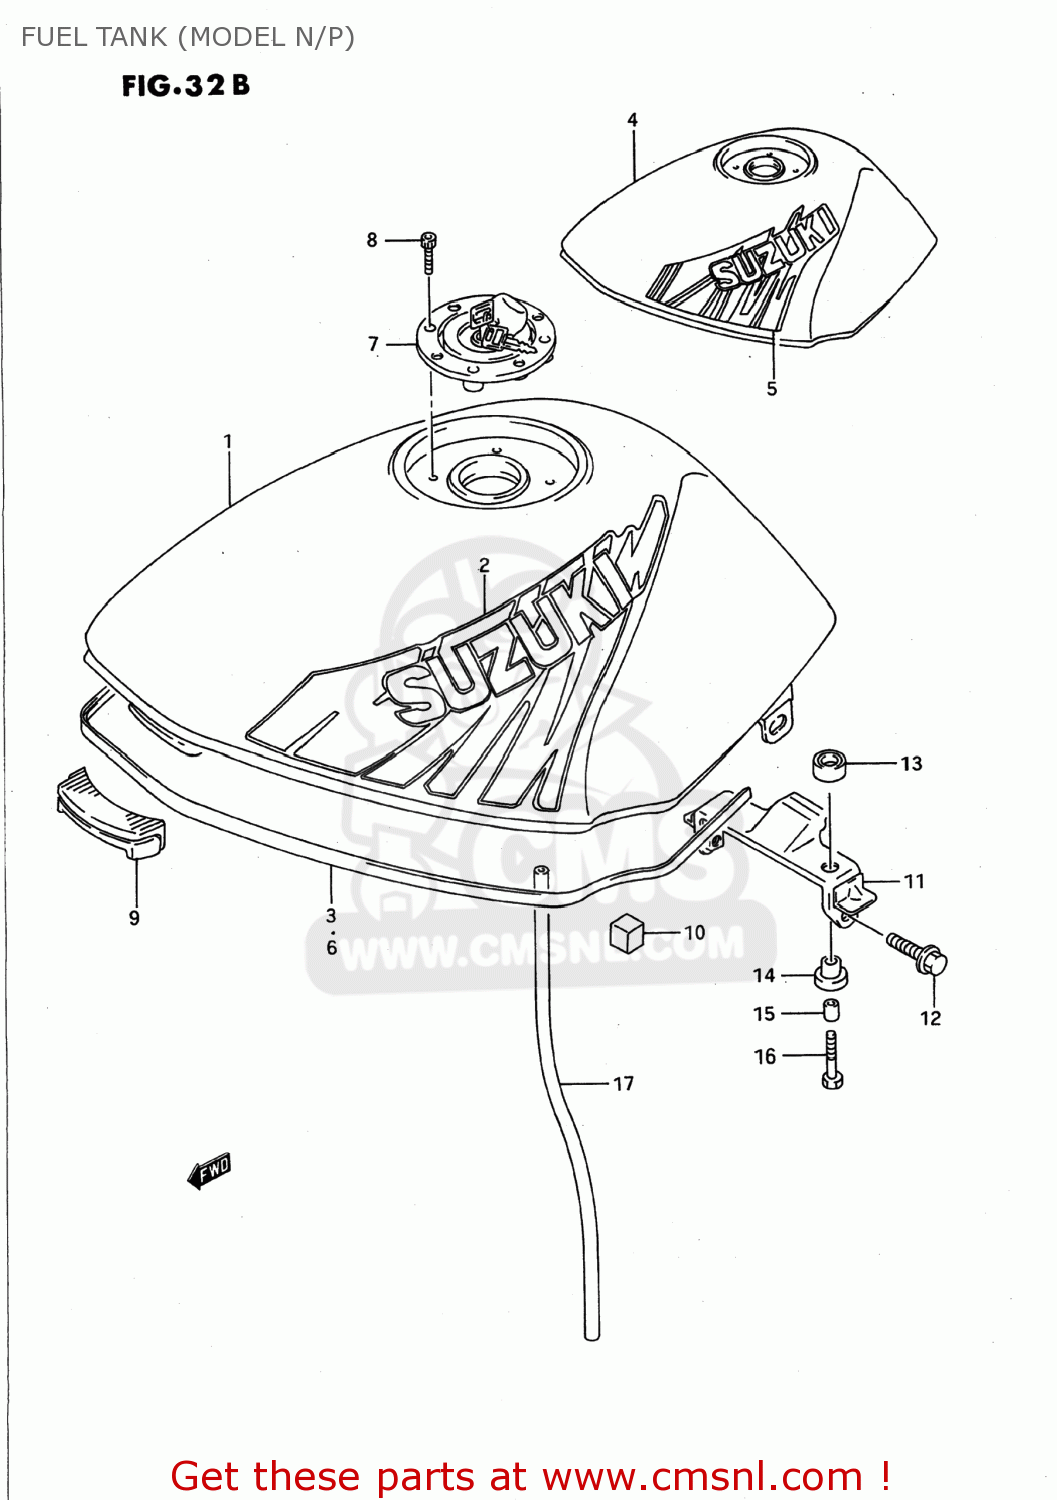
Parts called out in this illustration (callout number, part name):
1	TANK ASSEMBLY,FUEL
2	TAPE SET,FUEL TANK STRIPE
3	MOLDING
4	TANK ASSEMBLY,FUEL
5	TAPE SET,FUEL TANK
6	MOLDING
7	CAP SET,FUEL TANK
8	BOLT(5X20)
9	CUSHION,FUEL TANK FR
10	CUSHION,FUEL TANK SIDE
11	BRACKET COMP,FUEL TANK
12	BOLT
13	CUSHION
14	CUSHION
15	SPACER(6.1X9X18.2)
16	BOLT
17	HOSE,WATER DRAIN
